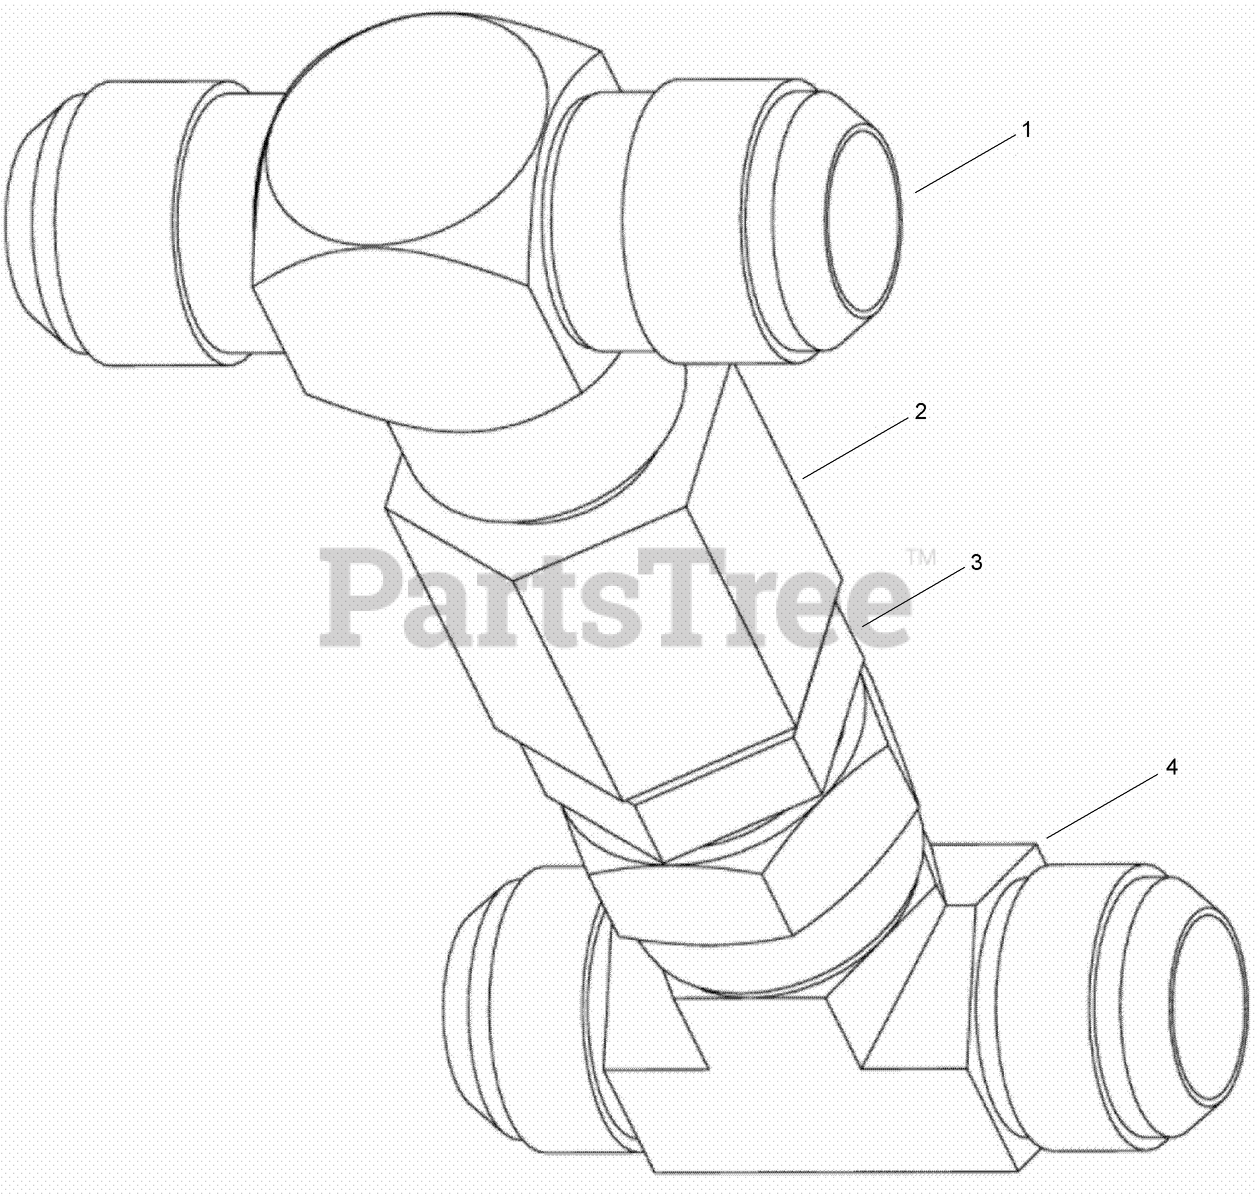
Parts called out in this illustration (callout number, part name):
1	FITTING-TEE
2	VALVE-CHECK
3	ADAPTER
4	ADAPTER-Tee, FJIC / MJIC
